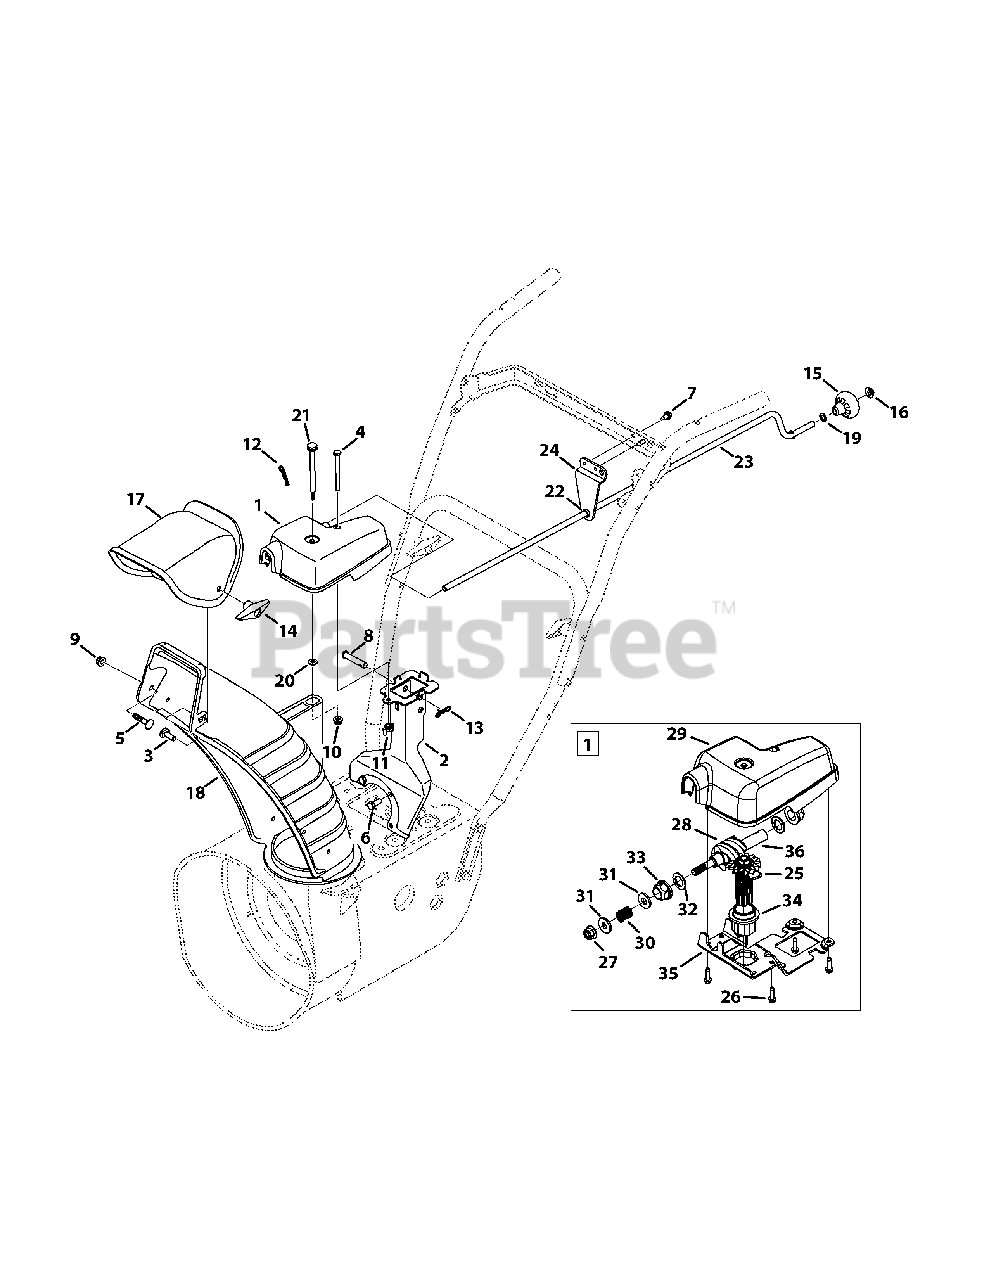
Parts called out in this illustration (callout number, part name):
1	Chute Rotation Gear Box
2	Chute Support Bracket (small block)
3	Carriage Bolt, 5/16-18 x 1.00
4	Hex Screw, 1/4-20 x 3.00
5	Carriage Bolt, 5/16-18 x .750
6	Hex Lock Screw, 5/16-24 x .750
7	Hex Washer Screw, 1/4-20 x .625
8	Clevis Pin, 3/8-1.87
9	Flange Lock Nut, 5/16-18
10	Flange Lock Nut, 1/4-20
11	Wing Nut, 1/4-20
12	Cotter Pin, .08 x 1.42
13	Bow-tie Cotter Pin
14	Wing Knob, 5/16-18
15	Shift Knob, .390
16	Push Cap, 3/8
17	Upper Chute
18	Lower Chute, 5.0
19	Flat Washer, .375 x .738 x .063
20	Flaw Washer, .25 x .630 x .0515
21	Shoulder Screw, .312 x 3.5 x 1/4-20
22	Plastic Bushing, .380 ID
23	Chute Crank
24	Support Rod Bracket
25	Gear Assembly
26	Screw, 12-16 x .75
27	Flange Lock Nut, 3/8-16
28	Worm
29	Gear Cover
30	Compression Spring, .39 x .60 x .88
31	Flat Washer, .380 x .93 x .110
32	Flat Washer, .625 x 1.0 x .067
33	Hex Bearing
34	Flange Bearing
35	Gear Bracket
36	Worm Shaft
